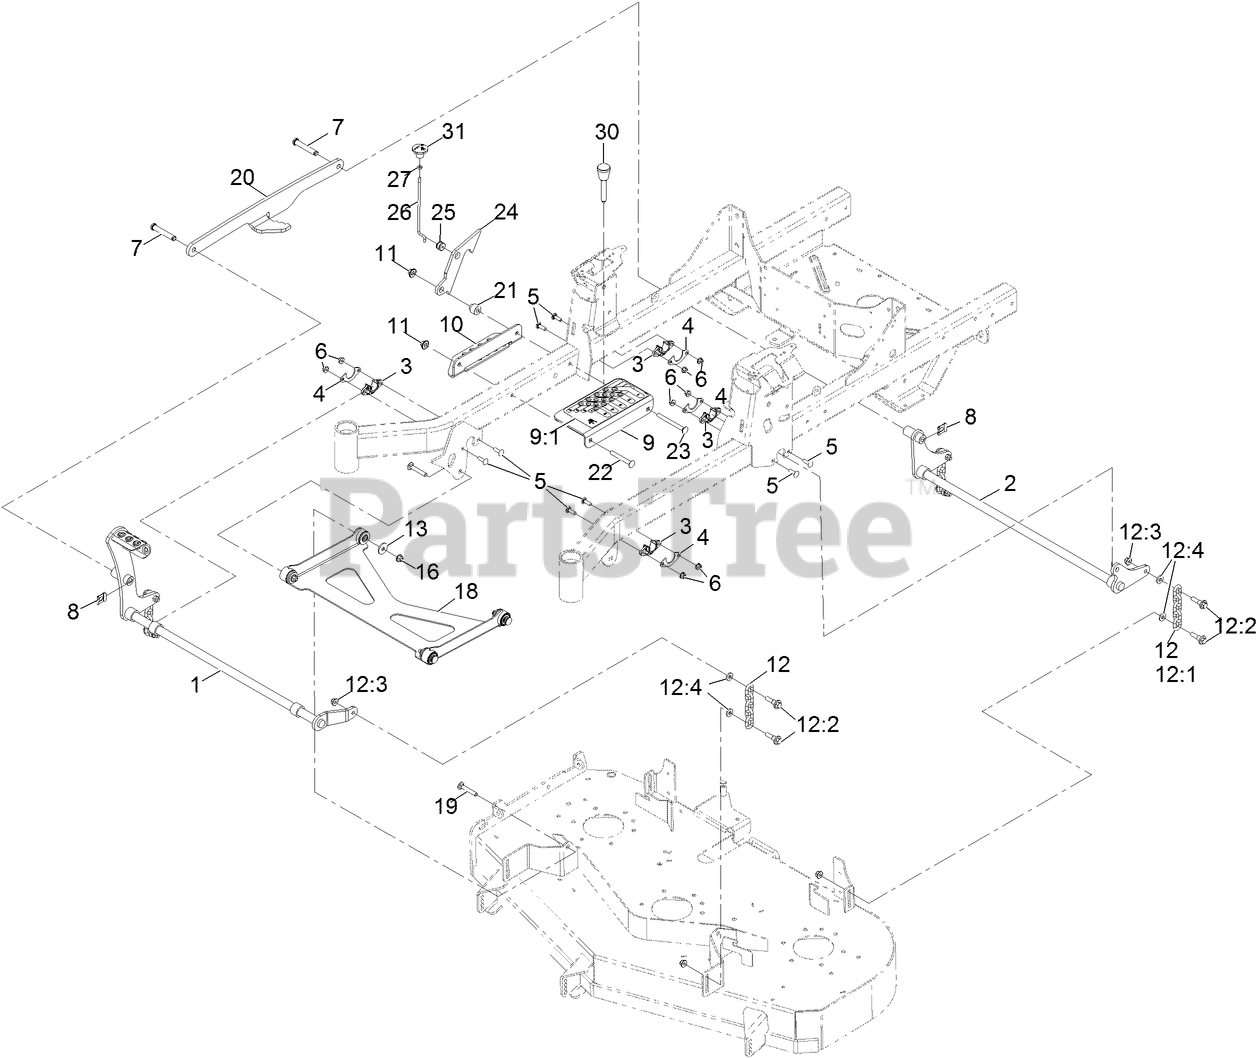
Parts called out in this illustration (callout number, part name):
1	SHAFT-LIFT, DECK
2	SHAFT-LIFT, DECK (REAR)
3	BUSHING-FLANGE
4	GUSSET-LIFT, DECK
5	SCREW-CARR
6	NUT-HF, NI
7	PIN-CLEVIS
8	CLIP-PIN
9	BRACKET ASM
9:1	DECAL-HOC
10	ANGLE-HOC, LOWER
11	NUT-FLANGE, NI
12	DECK CHAIN ASM
12:1	CHAIN-LIFT, DECK
12:2	BOLT-SHOULDER
12:3	NUT-HF, NI
12:4	SPACER
13	WASHER
16	NUT-HF, NI
18	DECK STRUT ASM
19	SCREW-CARR
20	LINK-LIFT
21	SPACER-STEPPED
22	SCREW-CARR
23	SCREW-CARR
24	PLATE-LOCK, TRANSPORT
25	GROMMET
26	ROD-LOCK, TRANSPORT
27	NUT-JAM
30	PIN-HOC
